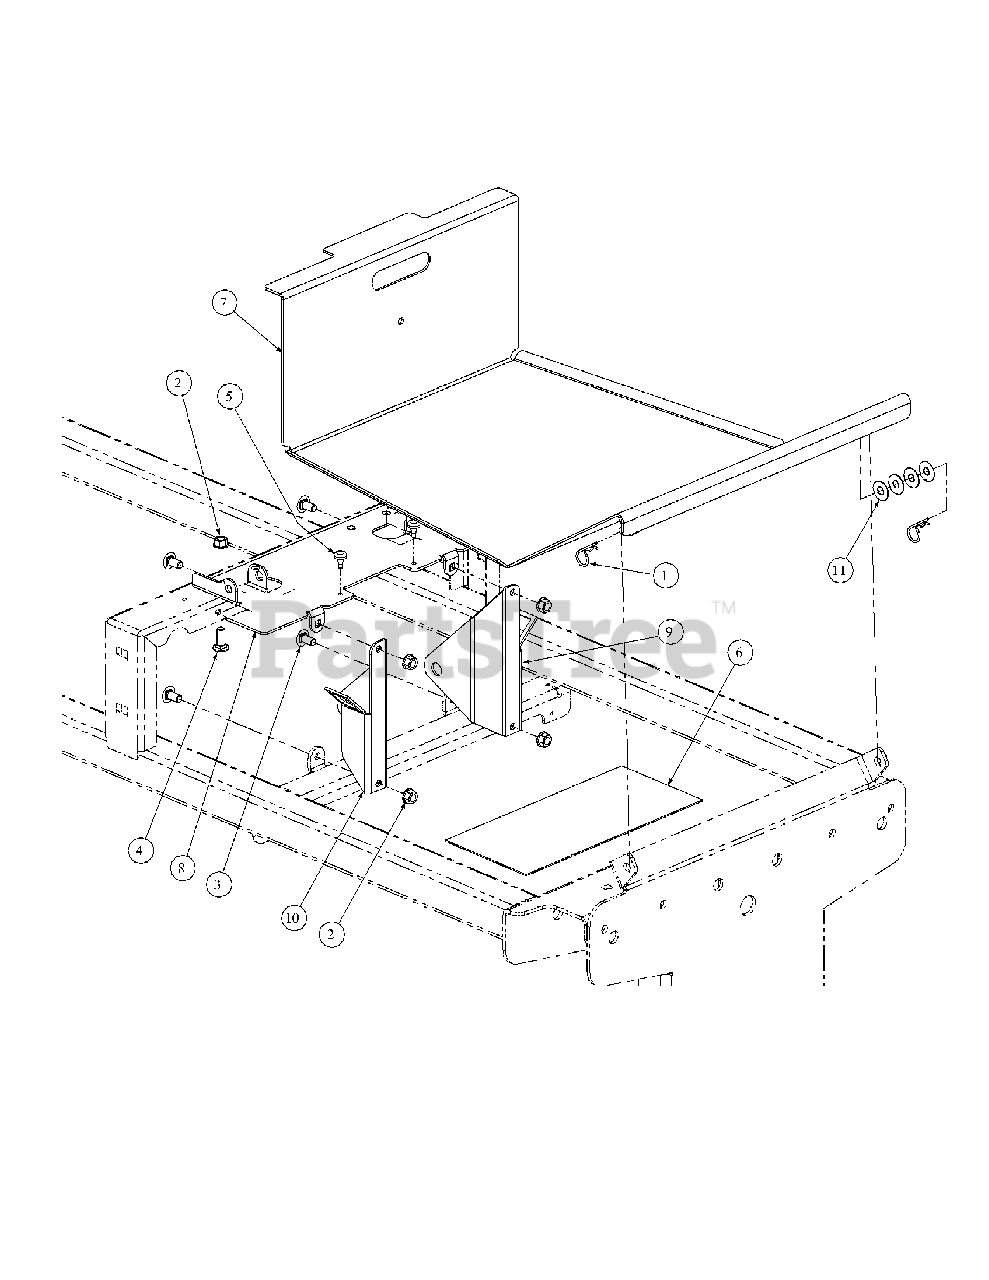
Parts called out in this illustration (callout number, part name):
1	Hair Pin, 3/8-1/2
2	Hex Nut, 3/8-16 Flange Lock
2	Hex Nut, 3/8-18 Flange Nut
3	Carriage Bolt, 3/8-16 x .75 Long
4	Carriage Bolt, 3/8-16 x 1
5	Rubber Bumper, .62 OD x .22 Thick
6	Label, Belt Routing and Lubrication
7	Floor Panel Assembly
8	Seat Mounting Bracket
9	Support, Seat Bracket, LH
10	Support, Seat Bracket, RH
11	Flat Washer, 3/8
